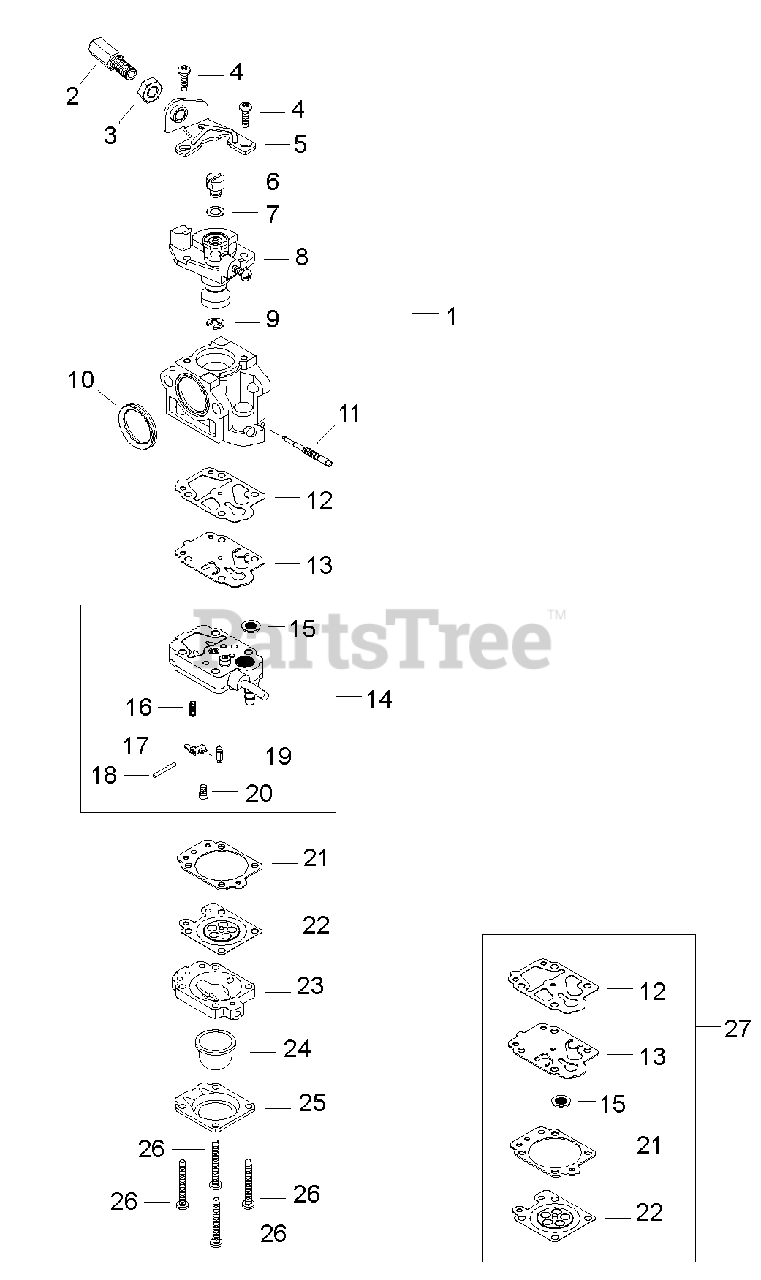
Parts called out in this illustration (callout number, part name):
2	ADJUSTER, THROTTLE CABLE
3	NUT, ADJUSTER LOCK M7
4	SCREW
5	BRACKET, THROTTLE CABLE
6	SWIVEL
7	WASHER
7-1	CARBURETOR
8	VALVE ASSY, THROTTLE
9	E-RING
10	RING, PACKING
11	NEEDLE, HIGH SPEED
12	GASKET, PUMP
13	DIAPHRAGM, PUMP
14	BODY ASSY, PUMP
15	SCREEN, FUEL INLET
16	SPRING, METERING LEVER
17	LEVER, METERING
18	PIN, METERING LEVER
19	VALVE, INLET NEEDLE
20	SCREW
21	GASKET, METERING DIAPHRAGM
22	DIAPHRAGM, METERING
23	BODY ASSY, PURGE
24	BULB, PURGE
25	RETAINER, PURGE BULB
26	SCREW
27	GASKET / DIAPHRAGM KIT
